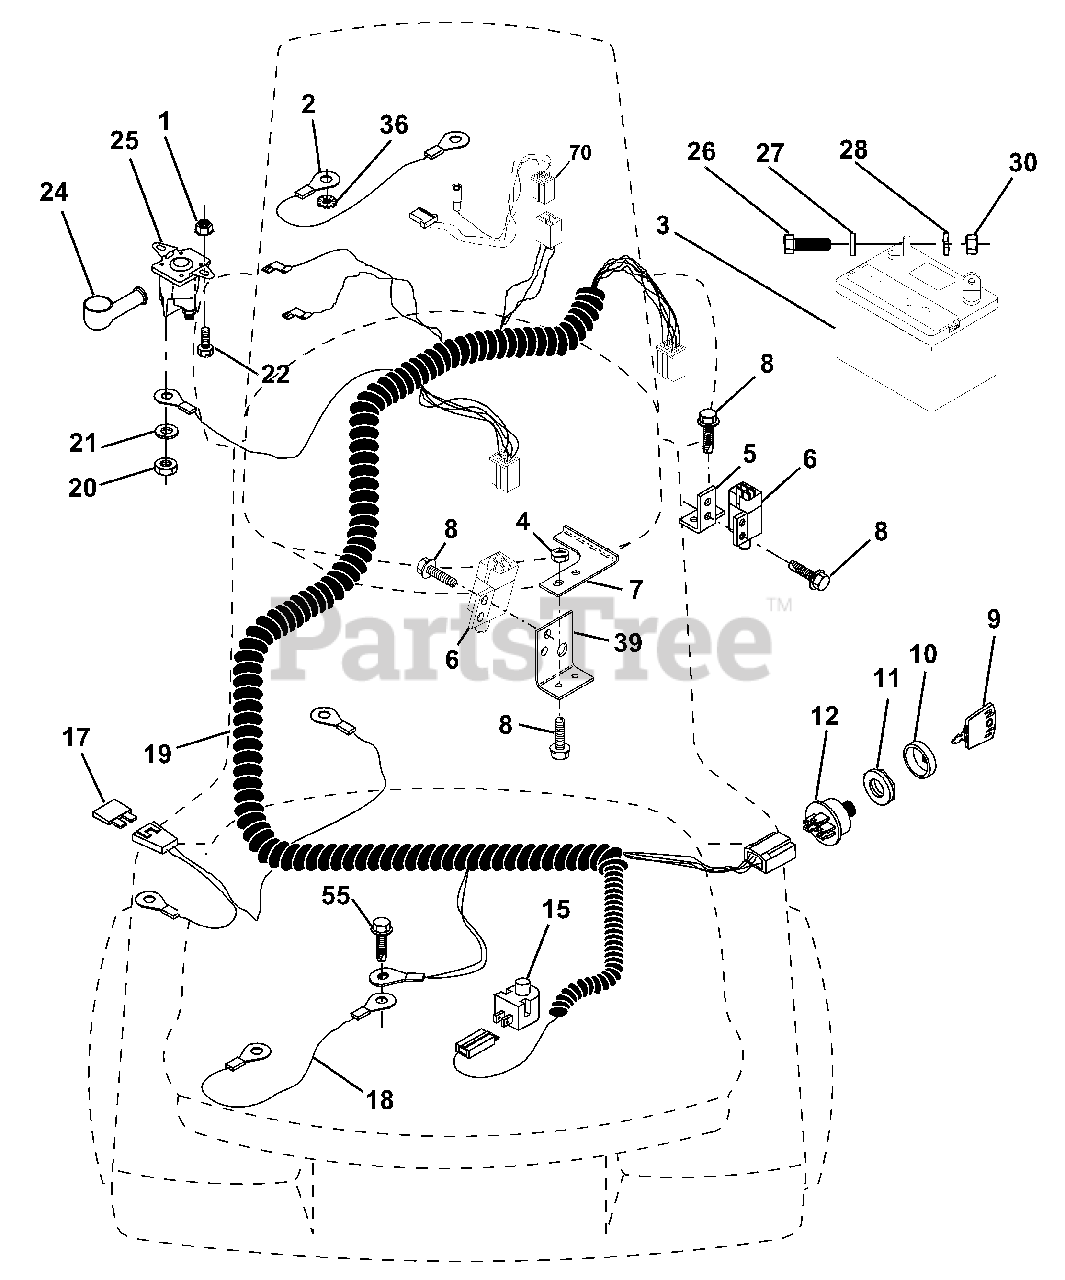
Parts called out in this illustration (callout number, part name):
1	Nut, Hex Keps 1/4-20
2	Assembly, Cable
3	Battery
4	Nut, Lock #10-24 UNC
5	Bracket, Switch
6	Switch, Interlock (4-terminal)
7	Keeper Actuator
8	Screw, Hex Hd. Tap #10-24 x 1/2
9	Key, Steel Delta
10	Cover, Key Ignition
11	Nut, Ignition
12	Switch, Ignition
15	Switch, Plunger
18	Assembly, Cable
19	Harness, Ignition
20	Nut, Hex Jam 1/4-20
21	Washer, Lock 1/4
22	Bolt, Fin. Hex 1/4-20 UNC x 1/2 Gr. 5
24	Cover, Terminal
25	Solenoid
26	Bolt, Hex Hd. 1/4-20 UNC x 3/4
27	Washer 9/32 x 5/8 x 16
28	Washer, Lock 1/4
30	Nut, Fin. Hex 1/4-20 UNC
36	Washer, Lock Inter. Tooth 1/4
39	Bracket, Switch Clutch
55	Screw Thdrol 5/16-18 x 1/2
70	Harness, Engine
